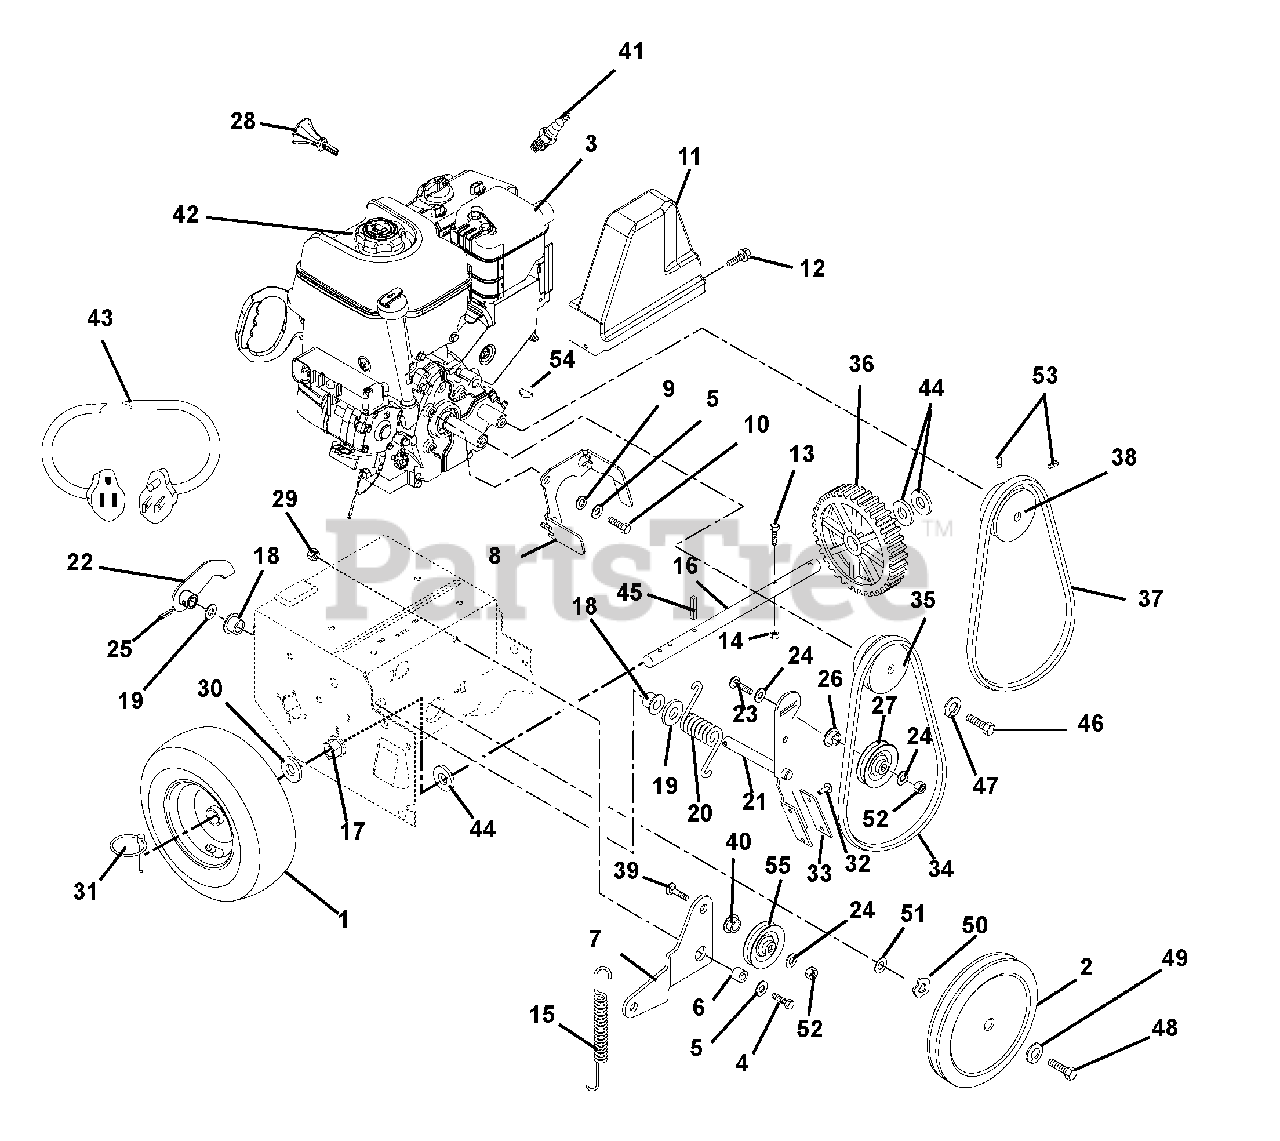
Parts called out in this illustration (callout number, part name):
1	TIRE/WHEEL, LH 13X4.00-6 PIN
2	PULLEY, 3L W/HUB, .625 X 8.0
3	ENGINE,5.5HP 120V PWRBILT SNOW
4	@BLT-HEX .31-18X.75 GR5 YWZC
5	@WSHR-FL-STL.38X.875X.083 YWZC
6	SPACER BUSHING .5 X .32 X .163
7	IDLER ARM
8	FINGER, BELT
9	WSHR-LK .312X.097 HVY YWZC
10	BLT-HEX .31-24X1.0 GR5 YZ EP80
11	BELT COVER
12	@SCR-TAP .25-20X.37 HWH YWZ TR
13	BLT-HEX .25-20X1.75 GR8 YWZC
14	@NUT-LK-CTR .25-20 YWZC
15	SG-TENS .047X.44X3.37 WLD 1.47
16	AXLE SHAFT, COMPACT W/PIN LOCK
17	BSHG-FLG .750X.873HEXX.53X1.18
18	BSHG-FLG .500X.625X.500X.750
19	WSHR-FL-STL .520X.810X.033YWZC
20	SG-TORS .148X1.0X1.53
21	CLUTCH ARM W/BRAKE PAD
22	ARM-CLUTCH
23	@BLT-RHDSHSQNK.31-18X1.25 G5YZ
24	@WSHR-FL-STL.38X.875X.083 YWZC
25	PIN-ROLL .156X.88
26	SPCR, BRG .315X.50X.688X.281
27	IDLER
28	KEY, IGNITION PUSH/PULL B&S
29	@NUT-LK-CTR .31-18 YWZC
30	WSHR-FL-STL.754X1.125X.062YWZC
31	PIN-LOK .31X1.75
32	RVT-TBLR .187X.437 RH ST PL
33	BRAKE LINING
34	BELT,4L TO BE REPLACED07200021
35	SHEAVE, ENGINE
37	V-BELT, 3L-COGGED
38	SHEAVE - CAMSHAFT
39	@BLT-RHDSHSQNK.31-18X1.25 G5YZ
40	BSHG-FLG .320X.671X.575X.895
41	PLUG, SPARK
42	CAP, FUEL - BRIGGS
43	CORD, ELECTRIC START CORD 120V
44	WSHR-FL-STL .755X1.25X.125 YZ
45	PIN-ROLL .188X1.25
46	BLT-HEX .38-24X1.0 GR5 YZ EP80
47	@WSHR-LK .38X.094 REG YWZC
48	BLT-HEX .25-28X.75 GR5 YZ EP80
49	WSHR-LK .250X.077 HVY YWZC
50	WSHR-WAVE .69X.84X.011
51	WSHR-THRST .625 X 1.0 X .03
52	@NUT-LK-CTR-JAM .31-18 YWZC
53	SCR-SET .31-18X.38 SKHCUPDL
54	KEY-WDRF .125X.625X.250 SAE5
55	IDLER-FLAT 1.75"X .670 PLASTIC
